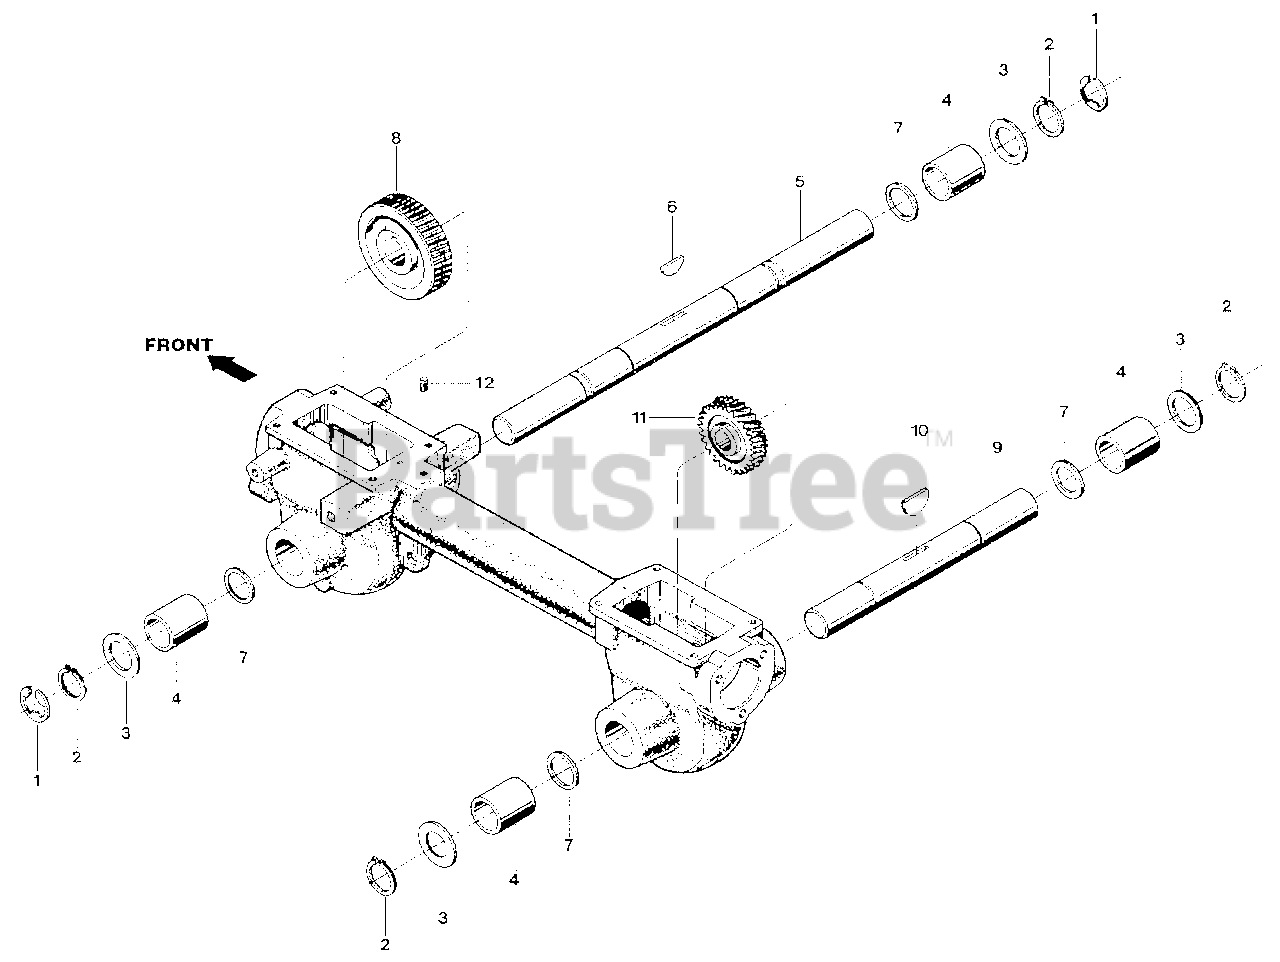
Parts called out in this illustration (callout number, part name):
1	Retainer, Snap Ring, "E" Type
2	Retainer, Snap Ring
3	Shim, 0.062" thick
4	Bronze Bushing
5	Wheel Shaft
6	Key, Hi-Pro, 1/4 x 1
7	Spacer
8	Worm Gear, Wheel Shaft
9	Tiller Shaft
10	Woodruff Key
11	Worm Gear, Tiller Shaft
